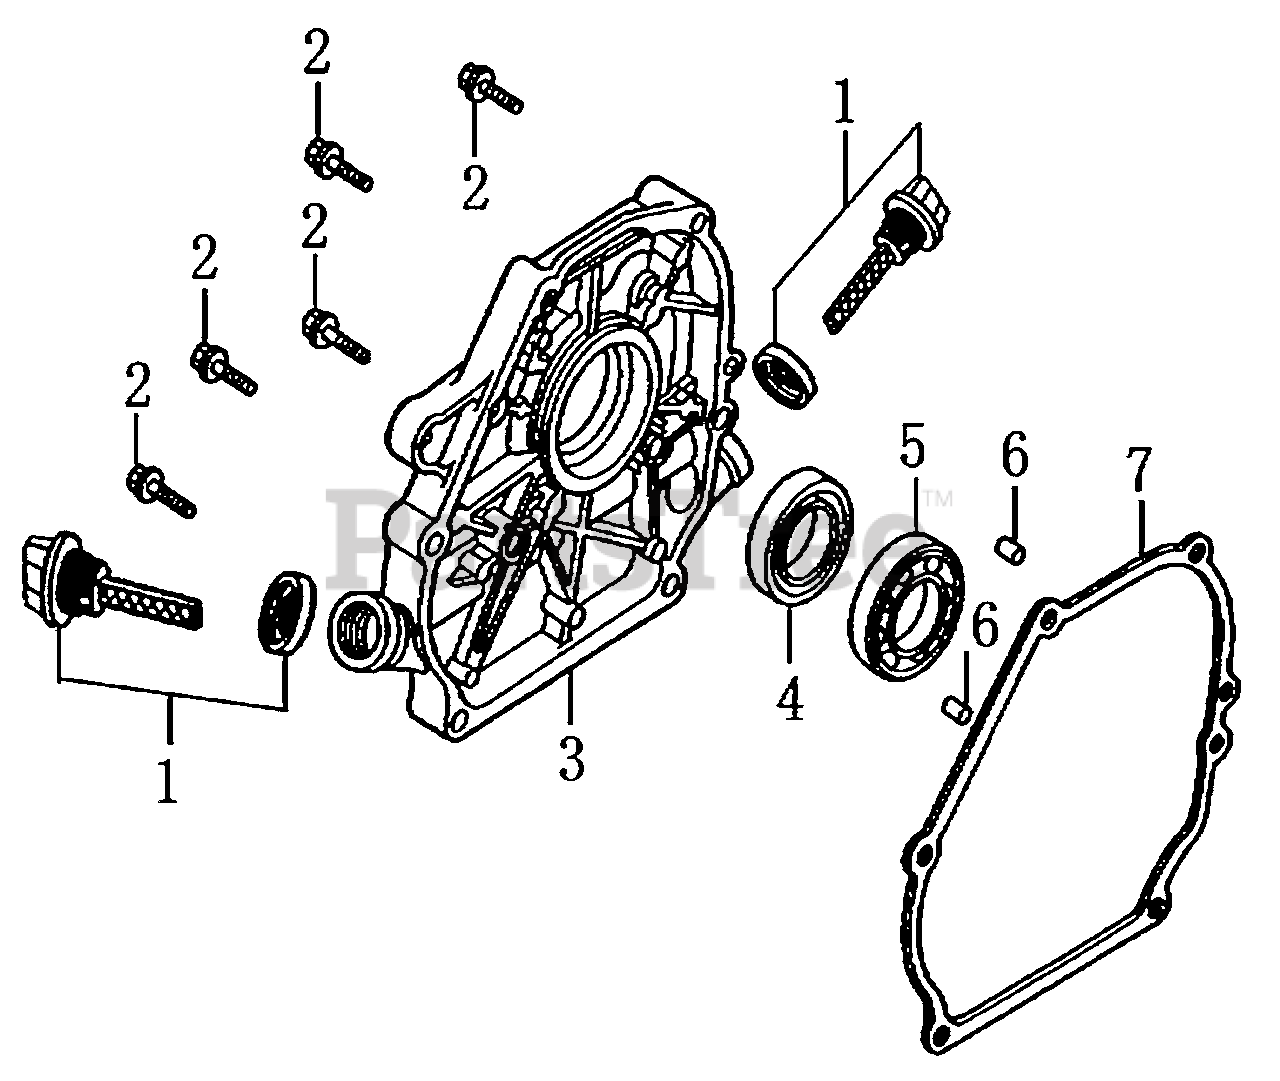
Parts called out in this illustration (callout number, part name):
1	GAUGE ASSY., OIL LEVEL
2	BOLT, FLANGE
3	COVER, CASE
4	SEAL, OIL 5X41.25X6
5	BEARING, RADIAL BALL
6	PIN, DOWEL
7	GASKET, CASE COVER
